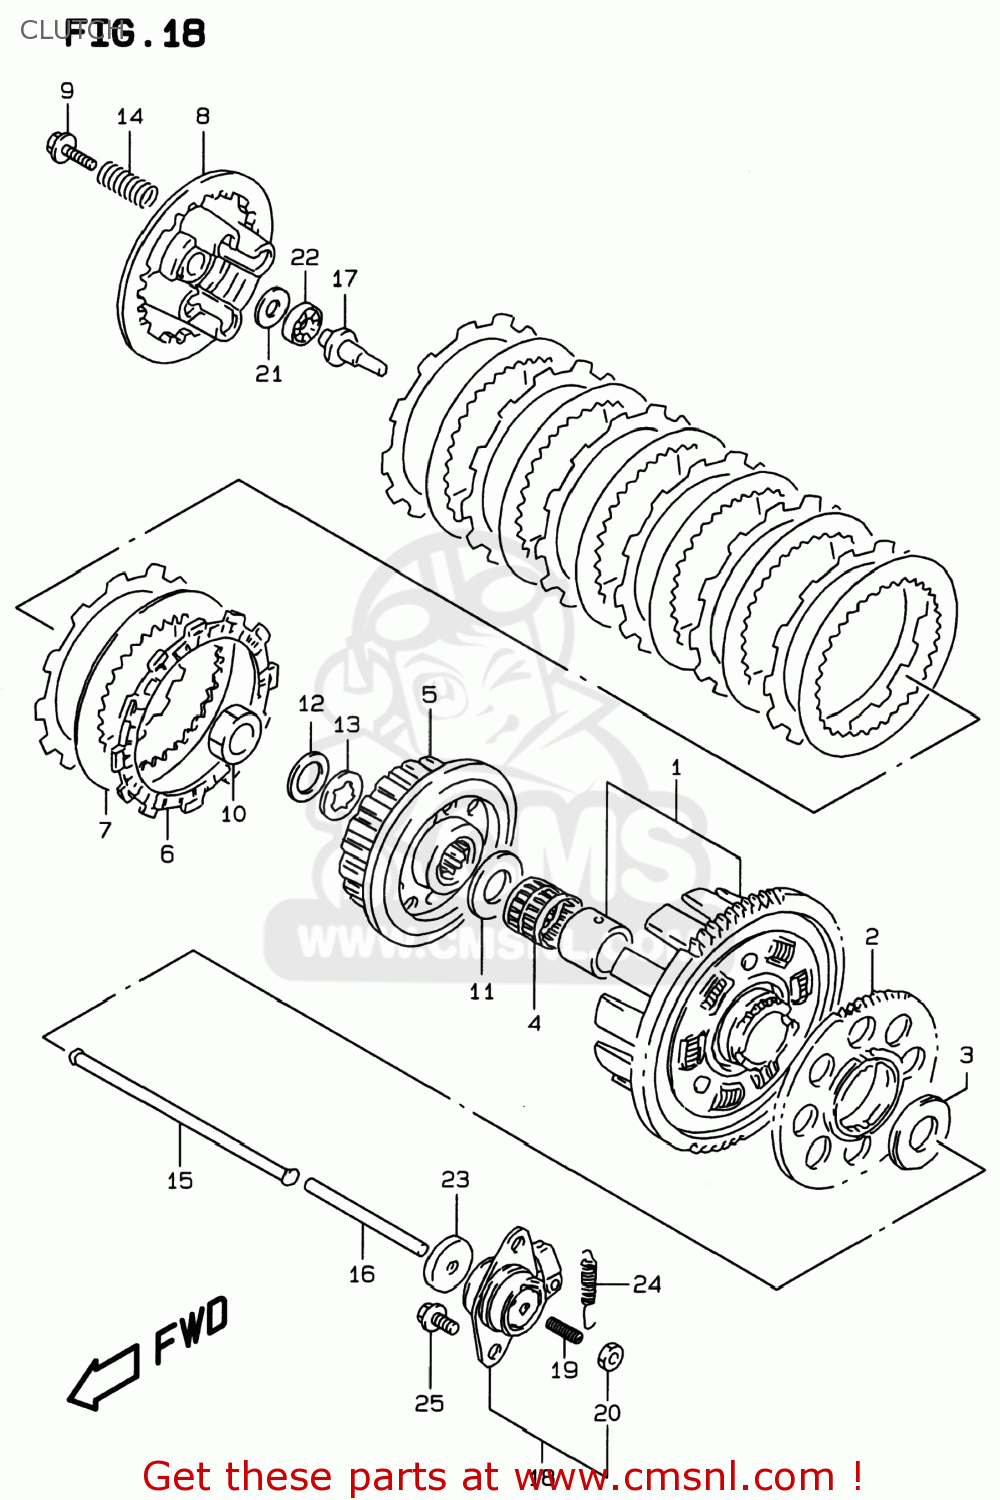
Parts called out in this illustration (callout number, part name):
1	GEAR ASSEMBLY,PRIMARY DRIVE
2	GEAR,GENERATOR DRIVE
3	WASHER(25X54X2.5)
4	BEARING(35X40X35.8)
5	HUB,CLUTCH SLEEVE
6	PLATE,CLUTCH DRIVE (NAS)
7	PLATE,CLUTCH DRIVEN (NAS)
8	DISC,CLUTCH PRESSURE
9	BOLT(6X16)
10	NUT
11	WASHER(25X50X2.5)
12	WASHER
13	WASHER,LOCK
14	SPRING
15	ROD,CLUTCH PUSH,R
16	ROD,CLUTCH PUSH,L
17	PIECE,CLUTCH PUSH
18	SCREW ASSY,CLUTCH RELEASE
19	SCREW(6X25)
20	NUT
21	WASHER(15.5X28X1)
22	BEARING(15X28X2)
23	SEAL,OIL(6X34X5.5)
24	SPRING
25	BOLT
